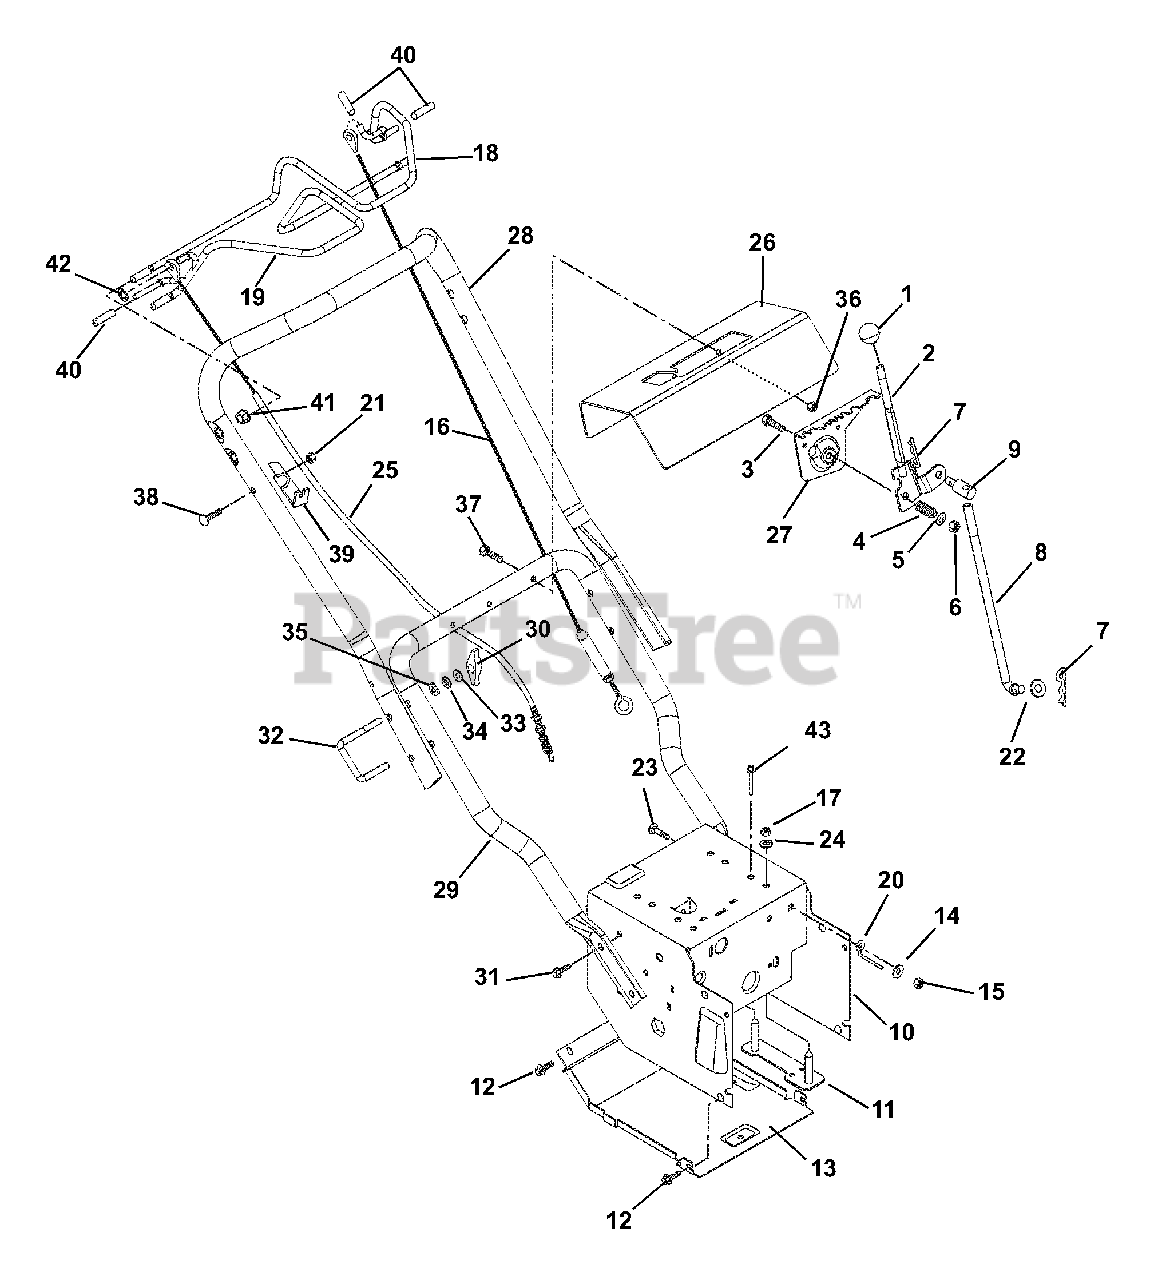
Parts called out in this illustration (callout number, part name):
1	KNOB,BALL -BLACK 1.47" .375-16
2	WMT, SHIFT LEVER
3	@BLT-HEX .38-16X2.00 GR5 YWZC
4	SG-COMP .125X.781X1.250
5	@WSHR-FL-STL.438X1.00X.083 YWZ
6	@NUT-LK-CTR .38-16 YWZC
7	PIN-HAIR INT .08X.18X1.18 YWZC
8	ROD, SHIFT
9	PIVOT, ROD (TRUNNION ) .50
10	FRAME, COMPACT SNOW
11	STRAP, ENGINE BOLT-WELDMENT
12	@SCR-TAP .25-20X.37 HWH YWZ TR
13	COVER BOTTOM
14	@WSHR-FL-STL.38X.875X.083 YWZC
15	@NUT-LK-CTR .31-18 YWZC
16	CABLE, TRACTION
17	@NUT-HEX .31-18 YWZC
18	BAIL, TRACTION
19	BAIL, AUGER
20	BELT FINGER LOWER
21	@NUT-LK-CTR .25-20 YWZC
22	@WSHR-FL-STL.531X1.06X.095YWZC
23	@BLT-RHDSSQNK .31-18X.75 G5YZ
24	WSHR-LK .312X.097 HVY YWZC
25	CABLE, AUGER
26	CONTROL PANEL W/DECAL
27	BRACKET, LEVER SHIFTER
28	HANDLEBAR W/DECAL
29	HANDLEBAR, LOWER
30	KNOB - WING .312-18 UNC
31	BLT SERHFWH .31-18X.62 GR5YWZC
32	J BOLT .31-18
33	@WSHR-FL-STL.38X.875X.083 YWZC
34	WSHR-LK .312X.097 HVY YWZC
35	WASHER,SADDLE-.320 X.937 X.062
36	@NUT-LK-TOP-FLG .25-20 YWZC
37	@BLT-HEX .25-20X1.50 GR5 YWZC
38	BLT-RDHDXLSQNK.25-20X1.25 G5ZC
39	ANCHOR, CABLE
40	CAP, VINYL, .25 ID
41	BSHG-FLG .325X.444X.440X.560
42	RG-RTNG-EXT .250X.010
43	RVT-POP .187X.45 DOME SS FBF64
